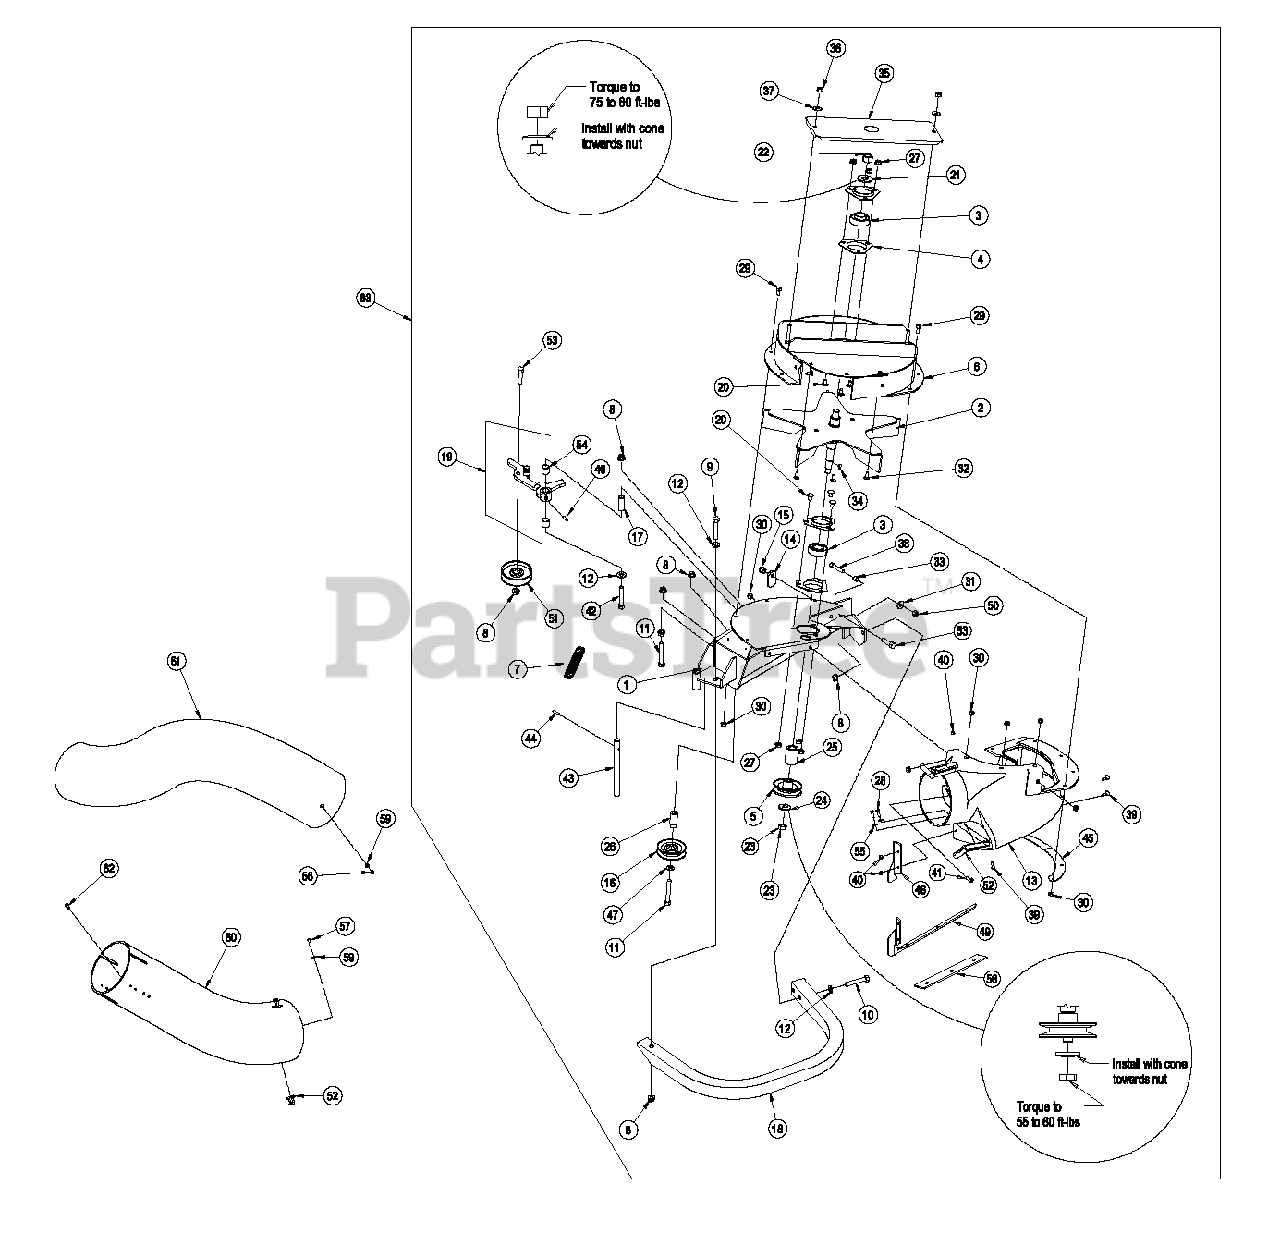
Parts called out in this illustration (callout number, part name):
1	WLD,BLOWER MOUNT
2	IMPELLER
3	BEARING
4	HOUSING-FLANGE
5	SHEAVE-BLOWER
6	ASM, UPPER HOUSING LZUV52
7	SPRING-IDLER
8	NUT-HHF, WHIZ
9	SCREW-HH
10	SCREW-HH
11	BOLT-CARR
12	WASHER-FLAT
13	CHUTE-BLOWER, SMALL
14	LATCH-CATCHER, GRASS
15	NUT-LOCK, NI
16	IDLER-INSIDE
17	BUSHING-PIVOT, IDLER
19	ASM, IDLER ARM - SERVICE
20	SCREW-CARR
21	WASHER-SPRING
22	NUT-HEX
23	NUT-JAM
24	WASHER-SPRING
28	SCREW-PPH
29	SCREW-HH
31	WASHER-SPRING
32	SCREW-CARR
33	BUSHING, LOCATOR
34	KEY-WOODRUFF
35	ASM, BEARING COVER
36	NUT-LOCK, NI
37	WASHER-FLAT
38	SCREW-HSH
39	SCREW-HEAD, TRUSS
42	SCREW-HSBH
43	SHAFT-CATCHER, GRASS
44	PIN-ROLL
45	PLATE-BACKING, BLOWER
46	FITTING-GREASE
47	WASHER-FLAT
48	PLATE, FILLER
49	PLATE, BLOCKER
50	NUT-HEX
51	IDLER-FLAT
52	LATCH DRAW
53	SCREW-HH
54	BUSHING
55	WASHER-FLAT
56	PLATE-REINFORCEMENT
57	SCREW-PPH
58	NUT-LOCK, NI
59	WASHER-FLAT
60	KIT,LOWER TUBE
61	TUBE-UPPER
62	SCREW-HWH
63	ASM, BLOWER LZUV52 - SERV
